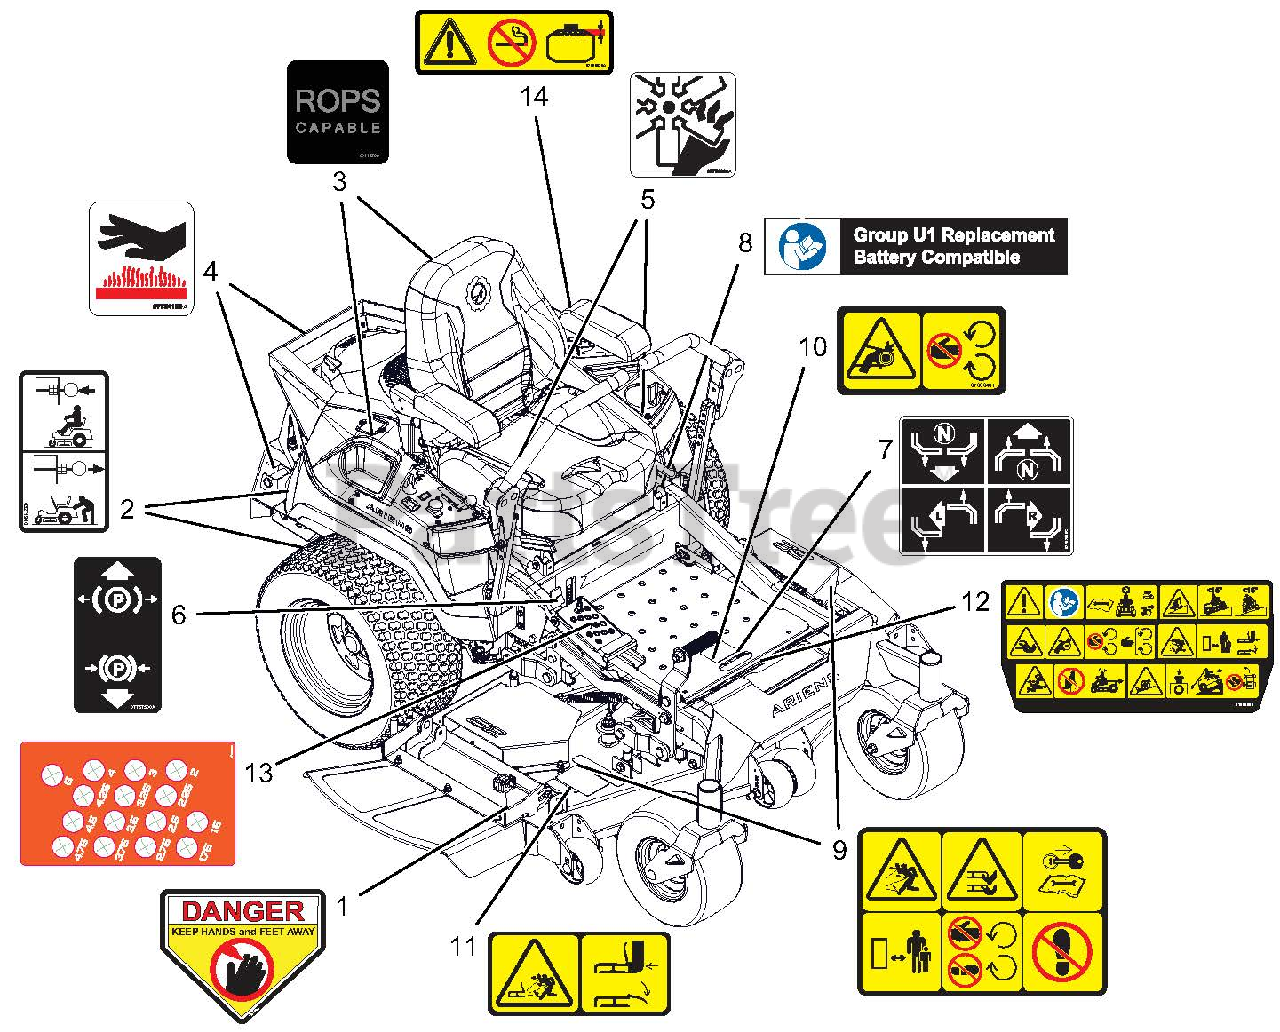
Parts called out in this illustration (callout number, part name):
1	DECAL, DANGER
2	DECAL, TRANSMISSION DISCONNECT
3	DECAL, ROPS LOCATION
4	DECAL, HOT SURFACE
5	DECAL, DANGER FAN
6	DECAL, PARKING BRAKE LEVER
7	DECAL, INSTRUCTIONAL-STEERING
8	DECAL, U1 BATTERY REPLACEMENT
9	DECAL, SAFETY - MOWER DECK
10	DECAL, SAFETY - GUARDING
11	DECAL, SAFETY - DECK GUARDING
12	DECAL, MAIN SAFETY
13	DECAL, ARIENS HOC
14	DECAL, FUEL WARNING
